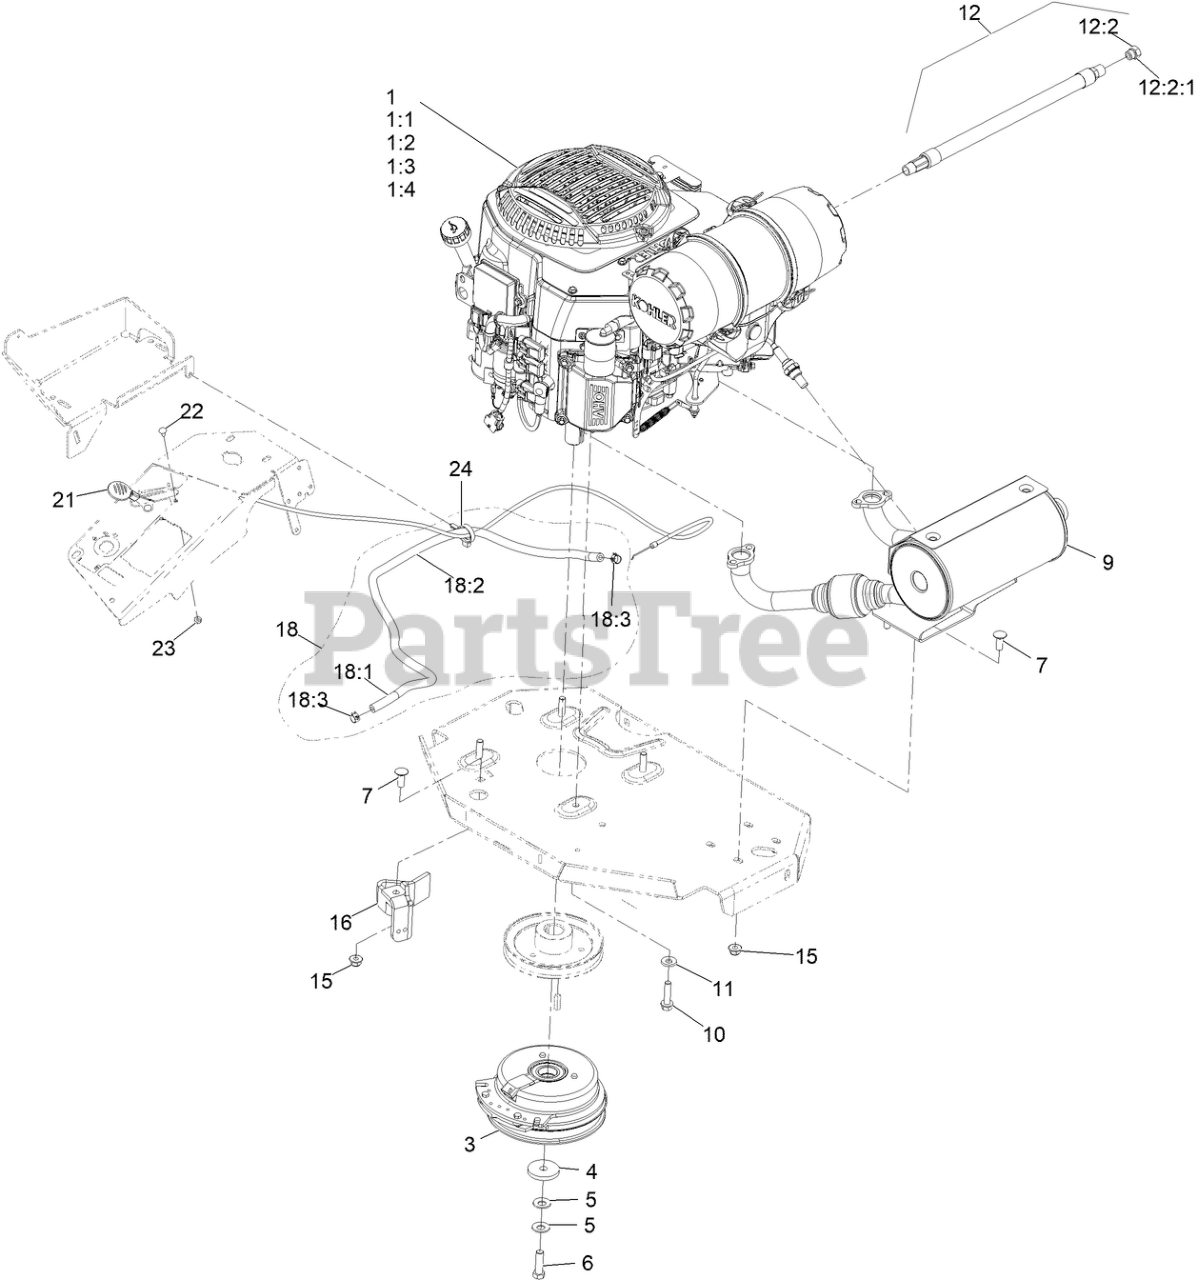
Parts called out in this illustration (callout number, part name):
1:1	Kohler 52 050 02-S Engine Oil Filter
1:2	Kohler 25 083 01-S Engine Air Filter
1:3	Kohler 25 083 04-S Safety Filter
1:4	Kohler 25 050 42-S Fuel Filter
3	CLUTCH KIT
4	WASHER-CLUTCH
5	WASHER-SPRING
6	SCREW-HH 7/16-20 X 1 1/2 W/LOCTITE
7	SCREW-CARR
9	KIT,MUFFLER
10	SCREW-HWH
11	WASHER-BELLEVILLE
12	OIL DRAIN HOSE ASM
12:2	PLUG-HH
12:2:1	O-RING
15	NUT-HF, NI
16	CLUTCH-ANCHOR
18	FUEL LINE ASM
18:1	HOSE-FUEL
18:2	SLEEVE-THERMAL
18:3	CLAMP-HOSE
21	ASM,THROTTLE CABLE
22	BOLT-CARR
23	NUT-LOCK, NI
24	CLAMP-HOSE
